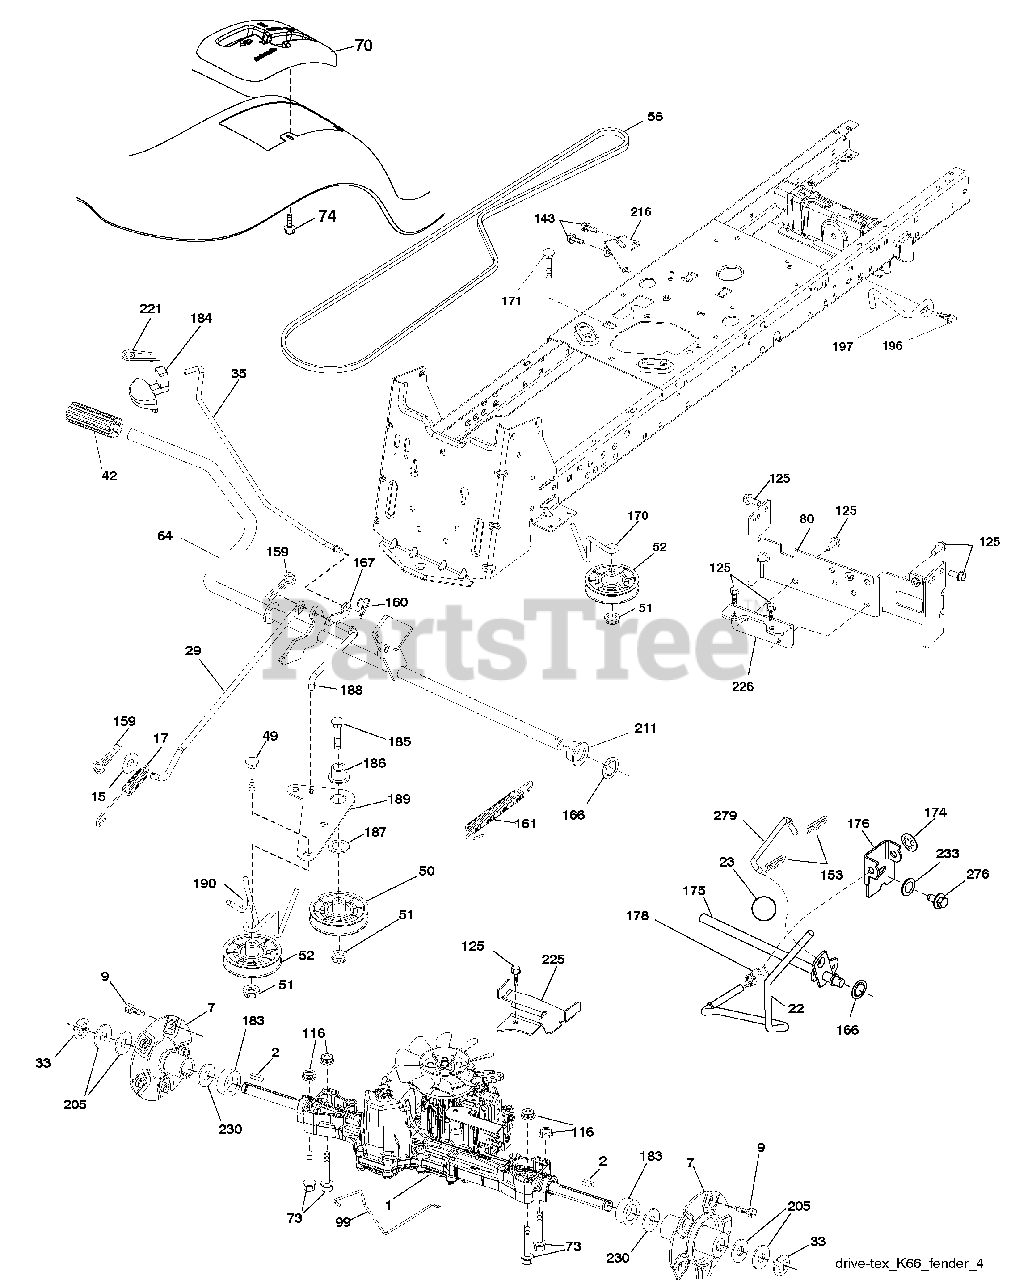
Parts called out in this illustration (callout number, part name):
1	Transaxle, TuffTorq K66 AD
2	Key
7	Hub Asm. Wheel
9	Bolt Hub Wheel
15	Washer 13/32 x 13/16 x 16 Ga.
17	Spring, Brake
22	Rod Shift
23	Knob
29	Rod, Brake
33	Ring E
35	Rod, Brake, Park
42	Cover, Foot Pedal
49	Bolt
50	Pulley Idler Flat
51	Lock Nut 3/8-16
52	Idler V-Groove 910" Offset
56	V-Belt, Drive
64	Shaft Asm. Pedal Brake Control
69	Washer 1 1/32 x 1 5/8 x 16 Ga.
70	Console Shift
73	Bolt Hex Flghd 5/16-18 Gr. 5
74	Screw Hx Wsh Hi-Lo 1/4 x 1/2 unc
80	Strap Torque
99	Rod Bypass
116	Nut Lock Hex Flange 5/16-18
125	Screw 5/16-18 x 3/4
143	Screw 5/16-18 x 1/2
153	Retainer Spring
159	Pin Cotter 1/8 x 3/4
160	Retainer Clip
161	Spring, Return, Clutch
166	Nut Push .625
167	Latch Brake Parking
170	Keeper Belt Centerspan
171	Bolt
174	Nut Push
175	Shaft Asm. Shift
176	Arm Clevis Rod Shift
178	Spring Shift
183	Spacer Axle
184	Handle Parking Brake
185	Bolt
186	Spacer Retainer
187	Washer
188	Link Clutch Ground Drive
189	Bellcrank Ground Drive
190	Keeper Bellcrank Ground Drive
196	Screw 3/8-16 x 1
197	Bracket Clutch Anti-Rotation
205	Washer 1-1/32 x 1-5/8 x 16 Ga.
211	Bushing Shaft
216	Bracket Pulley Idler
221	Retainer Spring Clip Handle
225	Keeper Belt Trans.
226	Bracket Mount Torque
230	Washer Thrust Axle
233	Washer Serrated
276	Bolt Fin. Hex 7/16-14 x 1 Gr. 5
279	Link Asm. Shift
